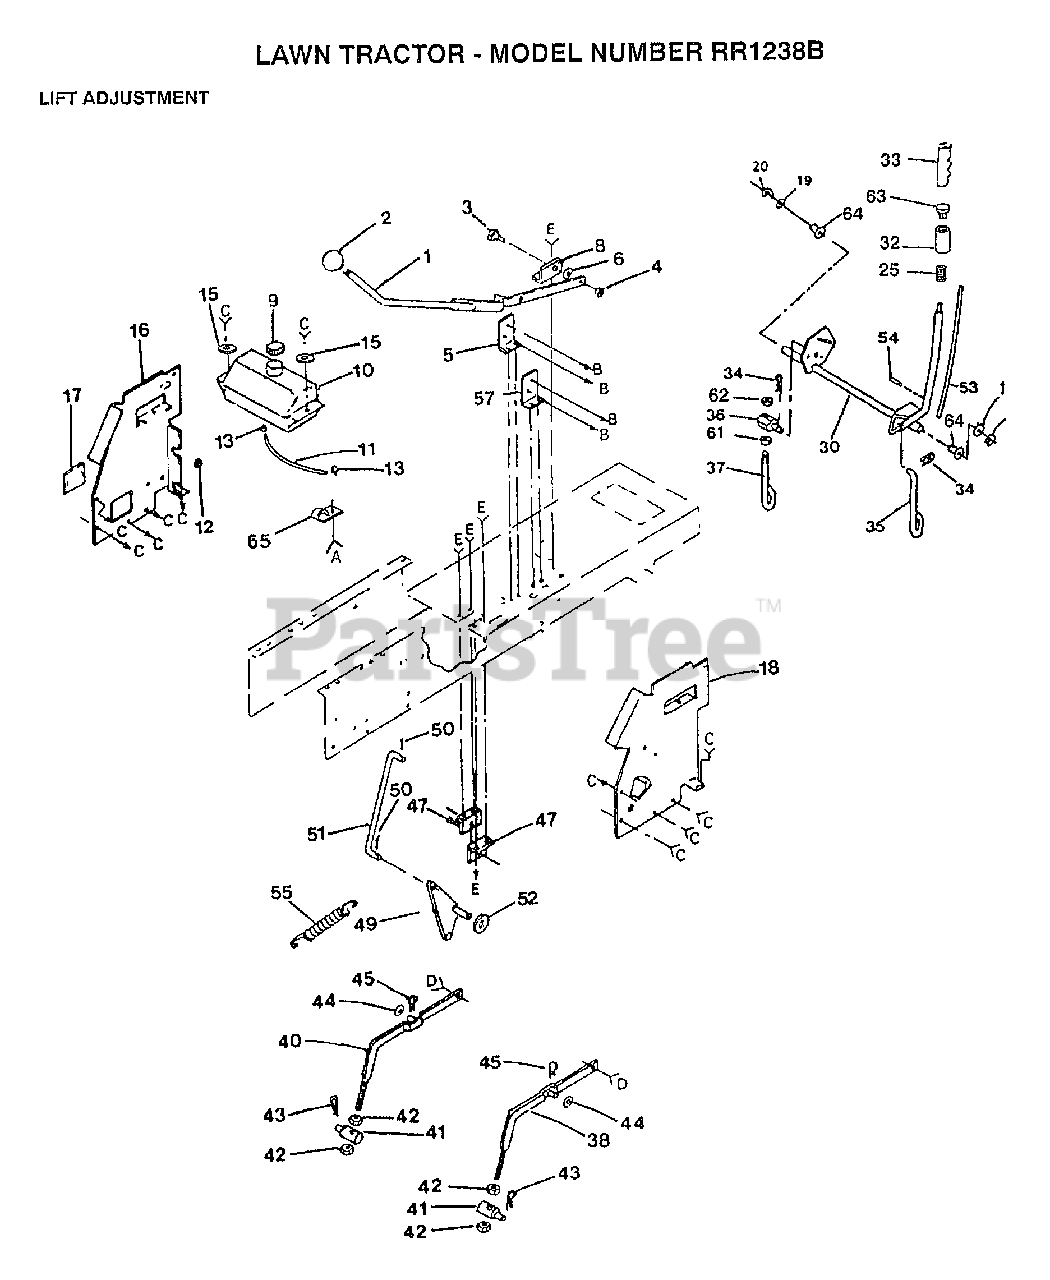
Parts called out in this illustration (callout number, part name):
2	KNOB T(3/8 HOLE)
3	"BOLT, SHOULDER LT"
5	"BRACKET,SWITCH LT"
8	"SUP,LVR,CLUTCH LT"
10	TANK.FUEL.LT.
11	FUEL LINE T
12	SNAP BUSHING T
13	HOSE CLAMP
15	WASHER GT
16	PANEL DASH LH
17	COVER ACCESS
19	WASHER
33	GRIP
35	LIFT LINK LT
37	PIVOT PIN T
38	RH SUSP ARM ASM
40	LH SUSP ARM ASM
42	NUT
43	SPRING H
45	SPRING.RETAINER
47	"BRKT,BELLCRAN T"
49	"T, BELLCRANK"
50	COTTER PIN
52	WASHER
54	PIN-GROOVE LT
57	BRACKET LT
61	NUT
64	NYLON BEARING
65	INSUL CLIP T
